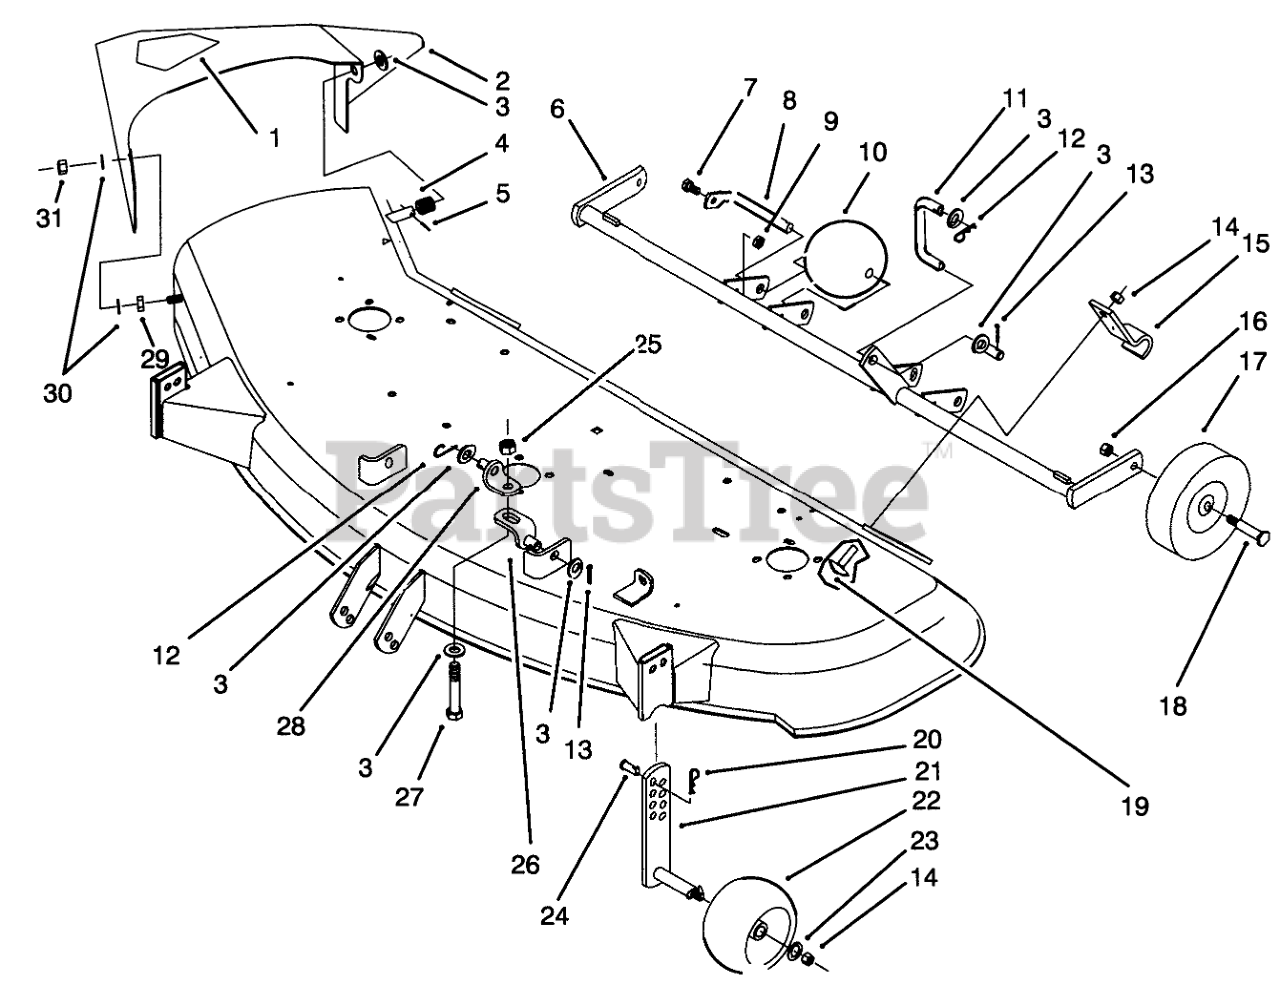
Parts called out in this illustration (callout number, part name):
1	DECAL-DANGER
2	Chute & Decal Assembly (Incl. ref. #1)
3	WASHER-FLAT
4	Spring
5	PIN-COTTER
6	Support-Gage Wheel
7	SCREW-HH
8	SHAFT-ROLLER
9	NUT-LOCK, NI
10	ROLLER
11	LINK-REAR
12	Hairpin
13	PIN-COTTER
14	NUT-LOCK, NI
15	Clamp
16	NUT-LOCK, SIDE
17	WHEEL
18	BOLT-SHOULDER
19	BOLT-CARR
20	Hairpin Cotter
21	GAGE-WHEEL
22	WHEEL-GAGE
23	WASHER-FLAT
24	PIN-CLEVIS
25	NUT-JAM
26	BRACKET-LIFT, LOWER
27	SCREW-HH
28	BRACKET-LIFT, UPPER
29	BUSHING-PIVOT
30	Washer
31	Nut
